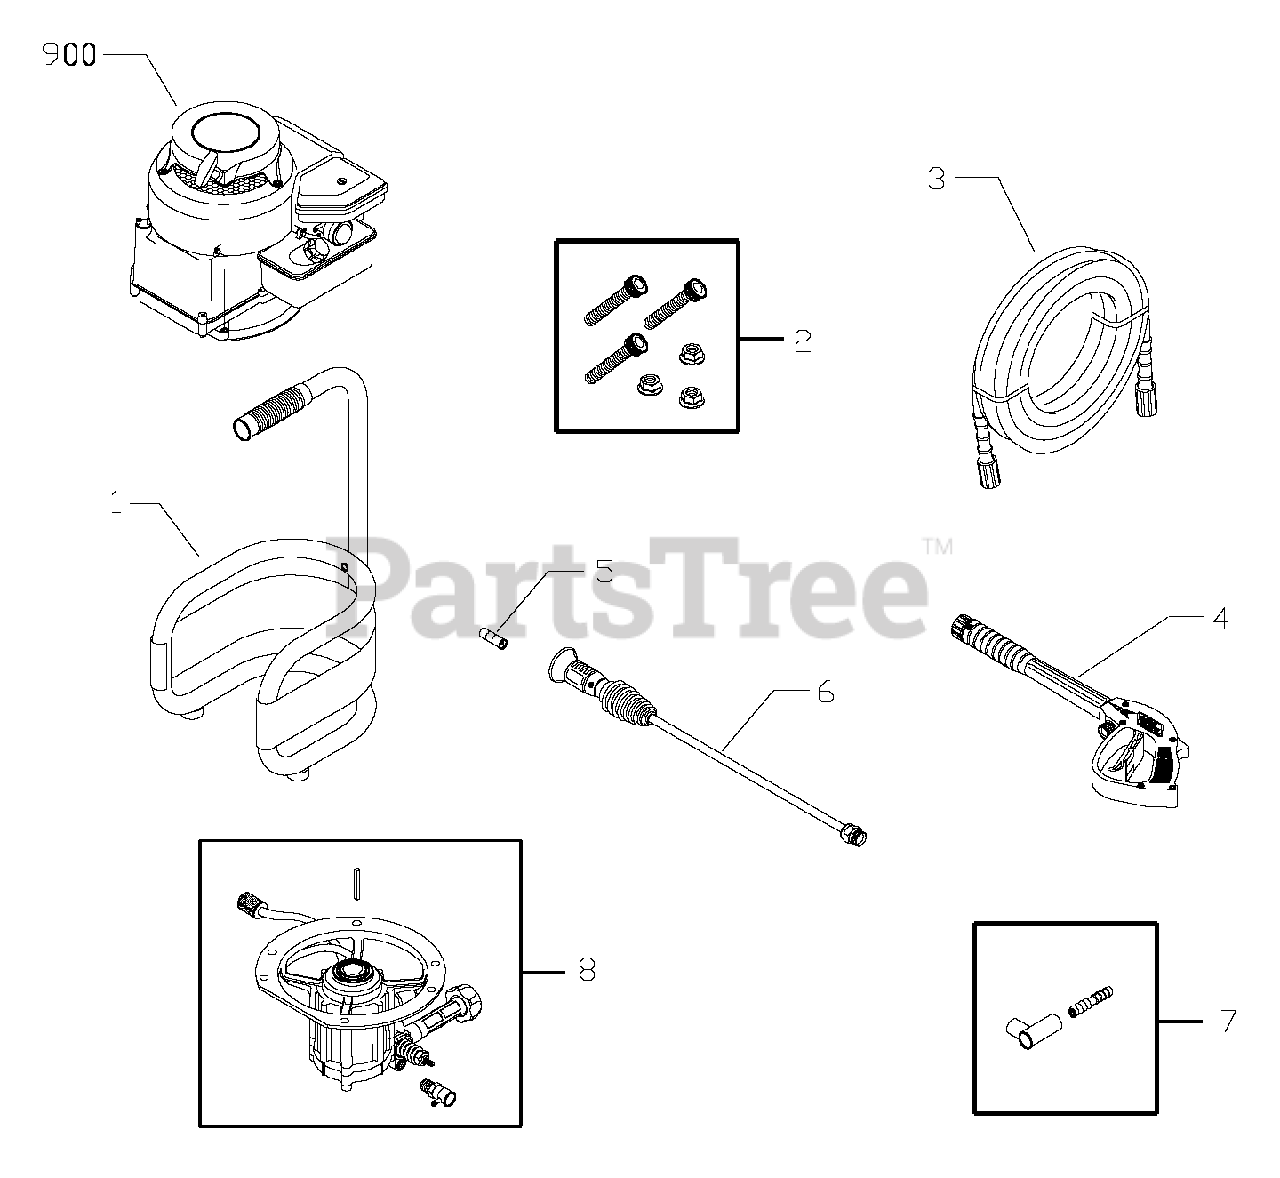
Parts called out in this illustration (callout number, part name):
1	ASSY, Base
2	KIT, Pump/Engine Mounting Hardware
3	HOSE, 25'
4	GUN
6	ASSY, Wand. Adjustable
7	KIT, Chem connector 90° w/Barb
900	ENGINE
